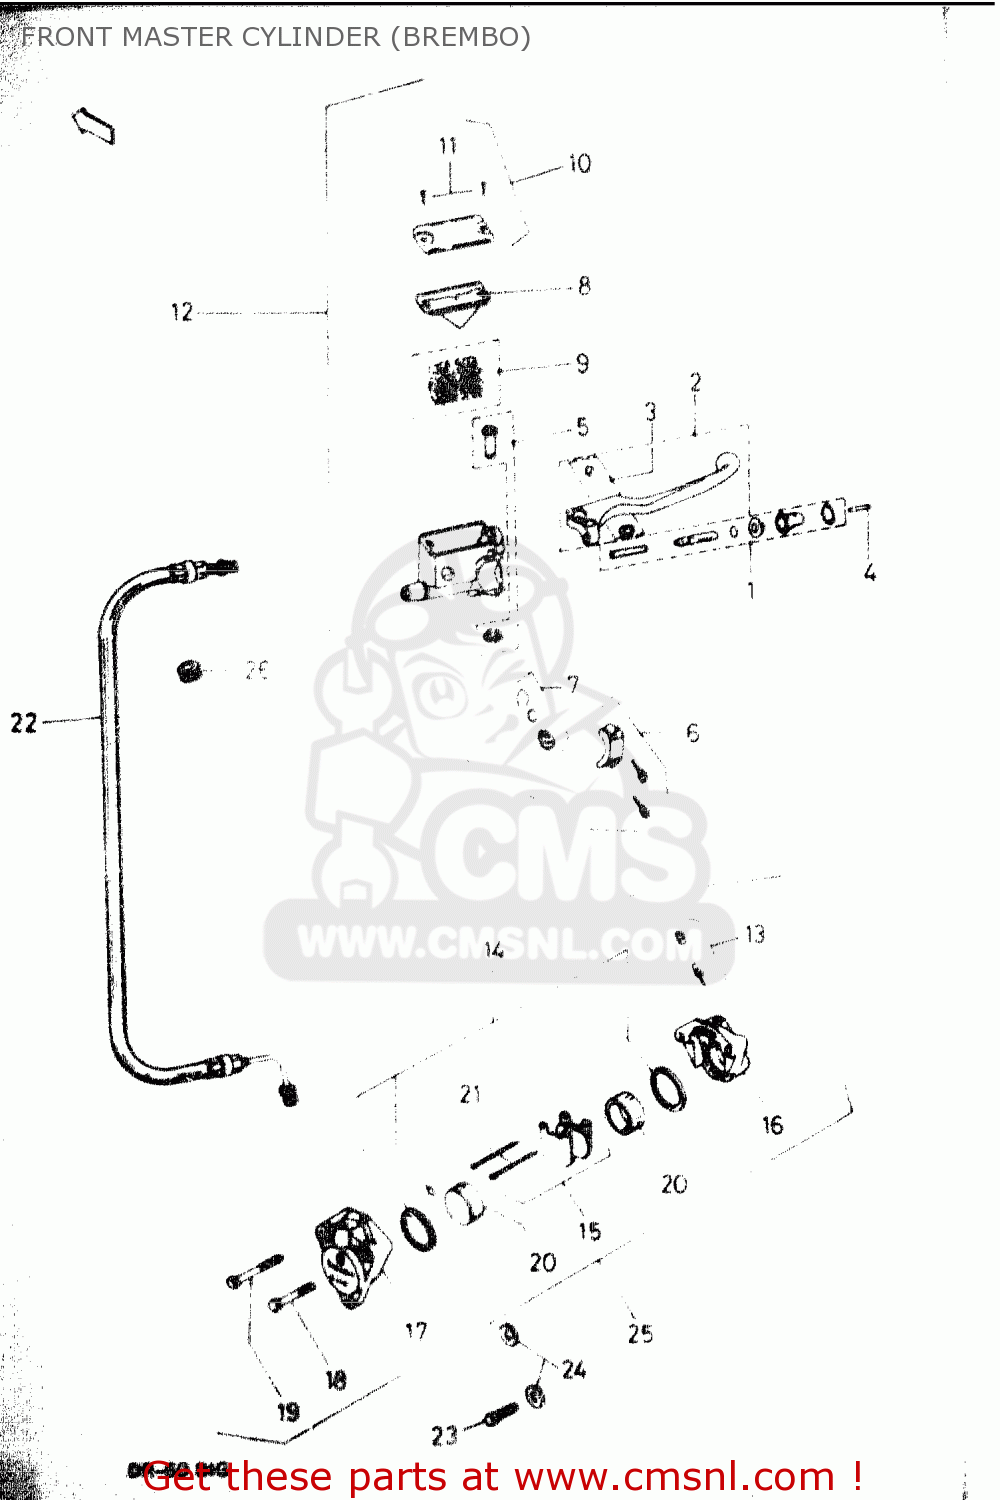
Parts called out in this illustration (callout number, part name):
1	PISTON & CUP SET
2	LEVER, RH
3	SCREW ADJUSTER
4	PIN, PUSHER
5	AXLE
6	HOLDER, WITH SCREW
7	SPIRIT LEVEL ASSY
8	MEMBRANE
9	FILTER
10	COVER, MASTER CYLINDER WITH SCREW
11	SCREW
12	LEVER ASSY
13	BLOWOFF VALVE
14	GASKET SET
15	PAT SET
16	SEMICALIPER, INNER
17	SEMICALIPER, OUTER
18	SCREW, SHORT
19	SCREW, LONG
20	PISTON
21	PIN
22	HOSE, FRONT BRAKE
23	SCREW M8X25 DIN 933/Y
24	WASHER B8 DIN 125/Y
25	CALIPER ASSY, FRONT
26	CUSHION
